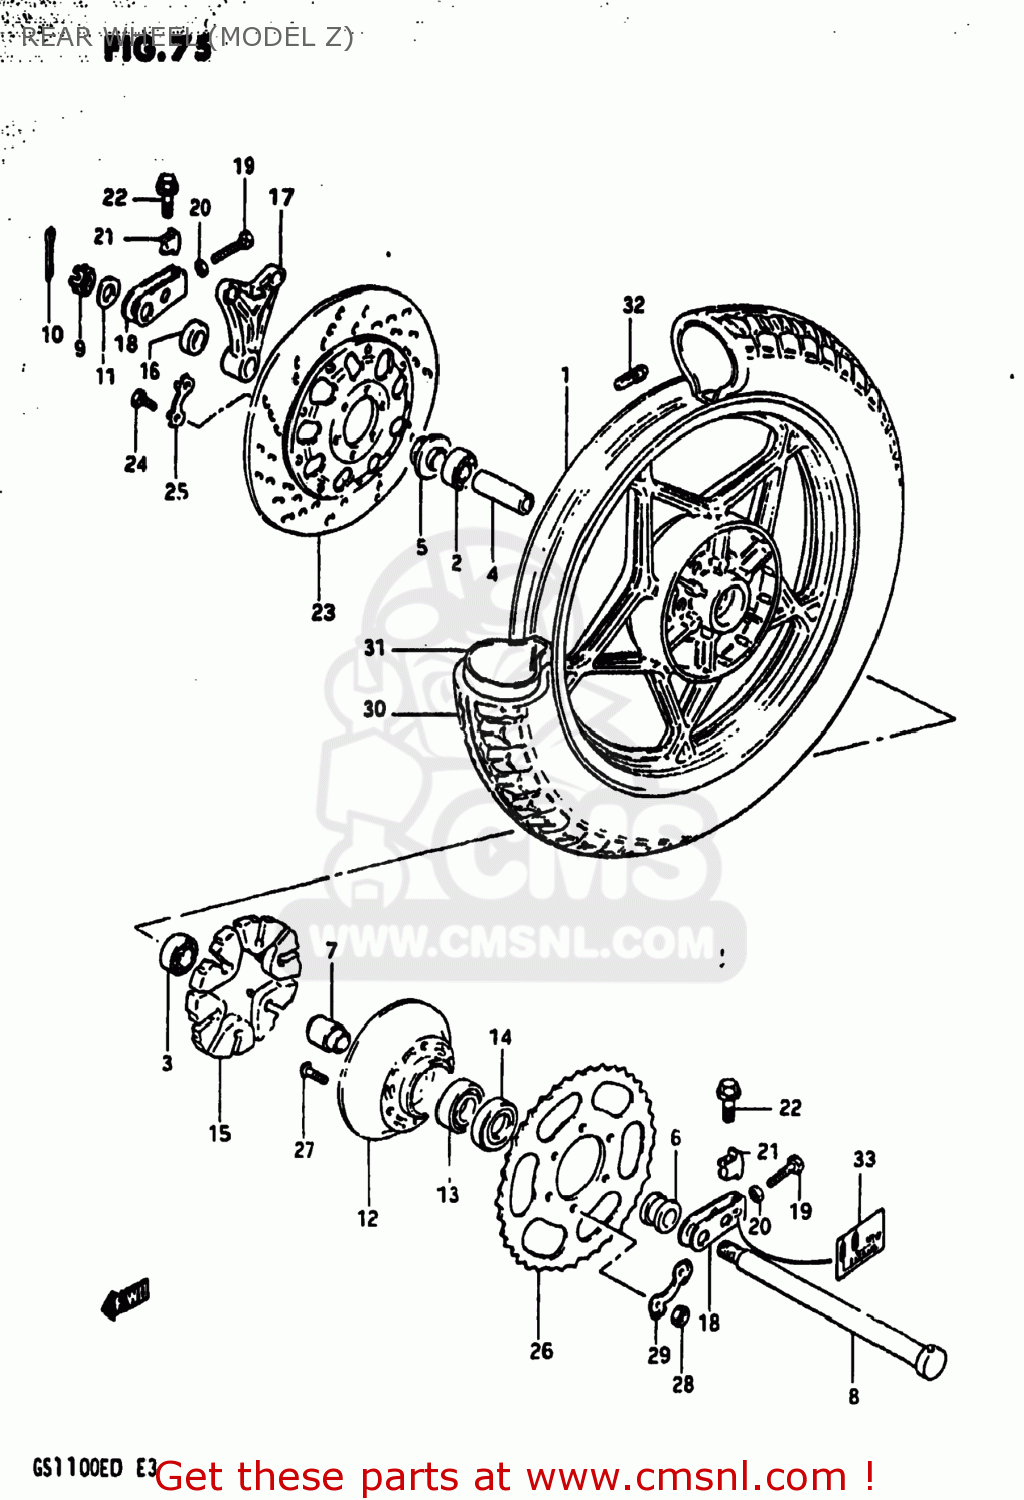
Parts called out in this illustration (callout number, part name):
1	CASTING WHEEL,REAR 2.50-
2	BEARING WHEEL REAR(20X47X14)
3	BEARING, LH
4	SPACER(20.5X28X88)
5	SPACER,REAR AXLE
6	SPACER(20X33X28.3)
7	SPACER,REAR HUB BEARING
8	AXLE,REAR
9	NUT 18MM
10	PIN,COTTER
11	WASHER(19X34X4)
12	DRUM,REAR SPROCKET MOUNT
13	BEARING
14	SEAL,OIL(33X62X7)
15	ABSORBER,REAR HUB SHOCK
16	SPACER(20X38X12)
17	BRACKET,RR,CALIPER
18	ADJUSTER,CHAIN
19	BOLT 8X50
20	NUT
21	SUPPORTER,CHAIN ADJUST
22	BOLT
23	DISC,RR BRAKE
24	BOLT(8X30)
25	WASHER
26	SPROCKET,REAR
27	BOLT
28	NUT
29	WASHER
30	TIRE 4.50V17
31	TUBE ASSEMBLY,WHEEL,INNER
32	BALANCER,WHEEL
33	LABEL,CHAIN WEAR INDICATOR
